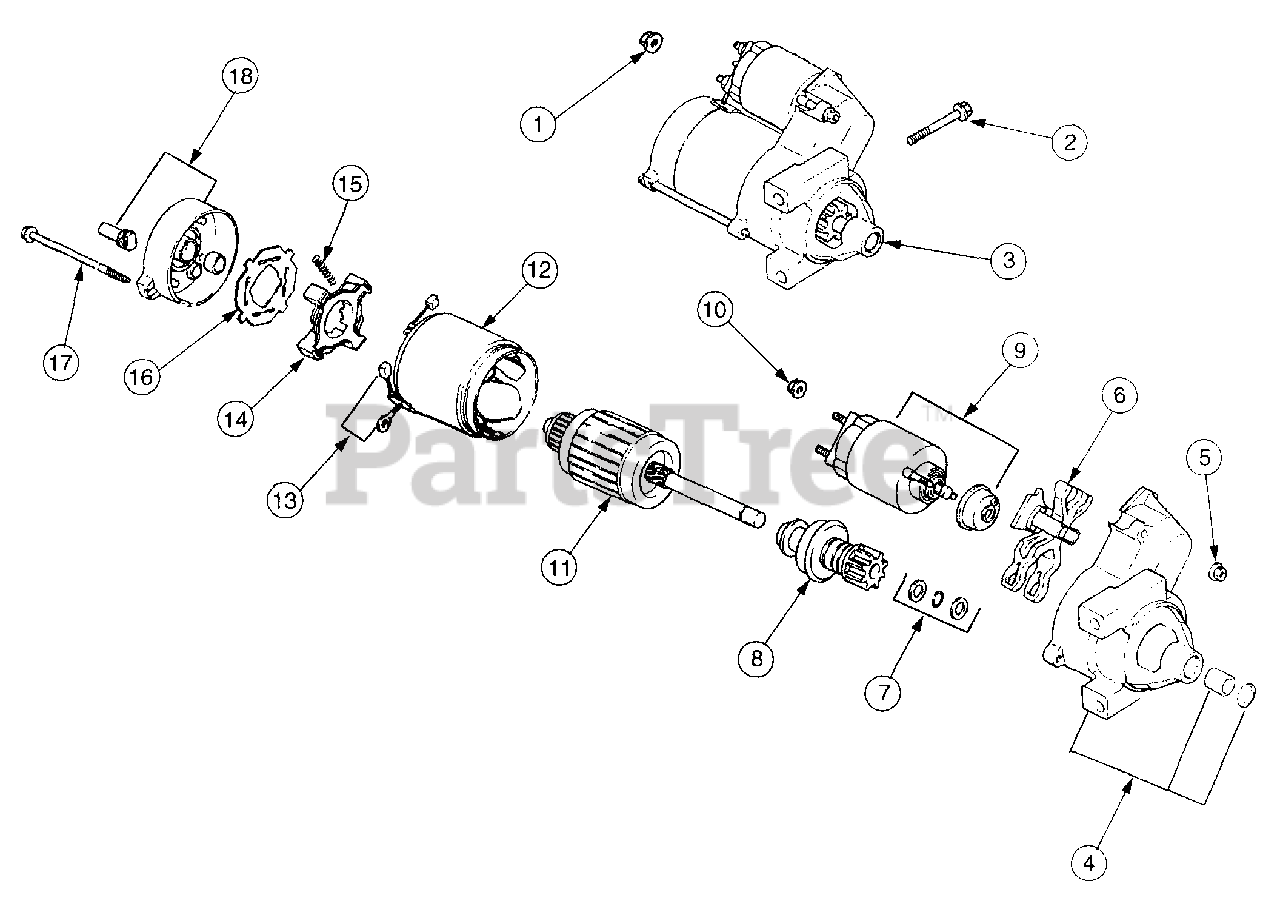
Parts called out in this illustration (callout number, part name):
1	Nut, Hex Flange M8 x 1.25
2	Screw, Hex Flange M8 x 1.25 x 80
3	Starter, Solenoid Shift Assy
4	Drive, End Cap
5	Nut, Starter
6	Lever, Starter Drive
7	Kit, Starter Repair
8	Drive, Pinion
10	Nut, Starter
11	Armature, Starter
13	Kit, Brush and Spring
14	Holder, Brush
15	Spring, Brush
18	Commutator, End Cap
